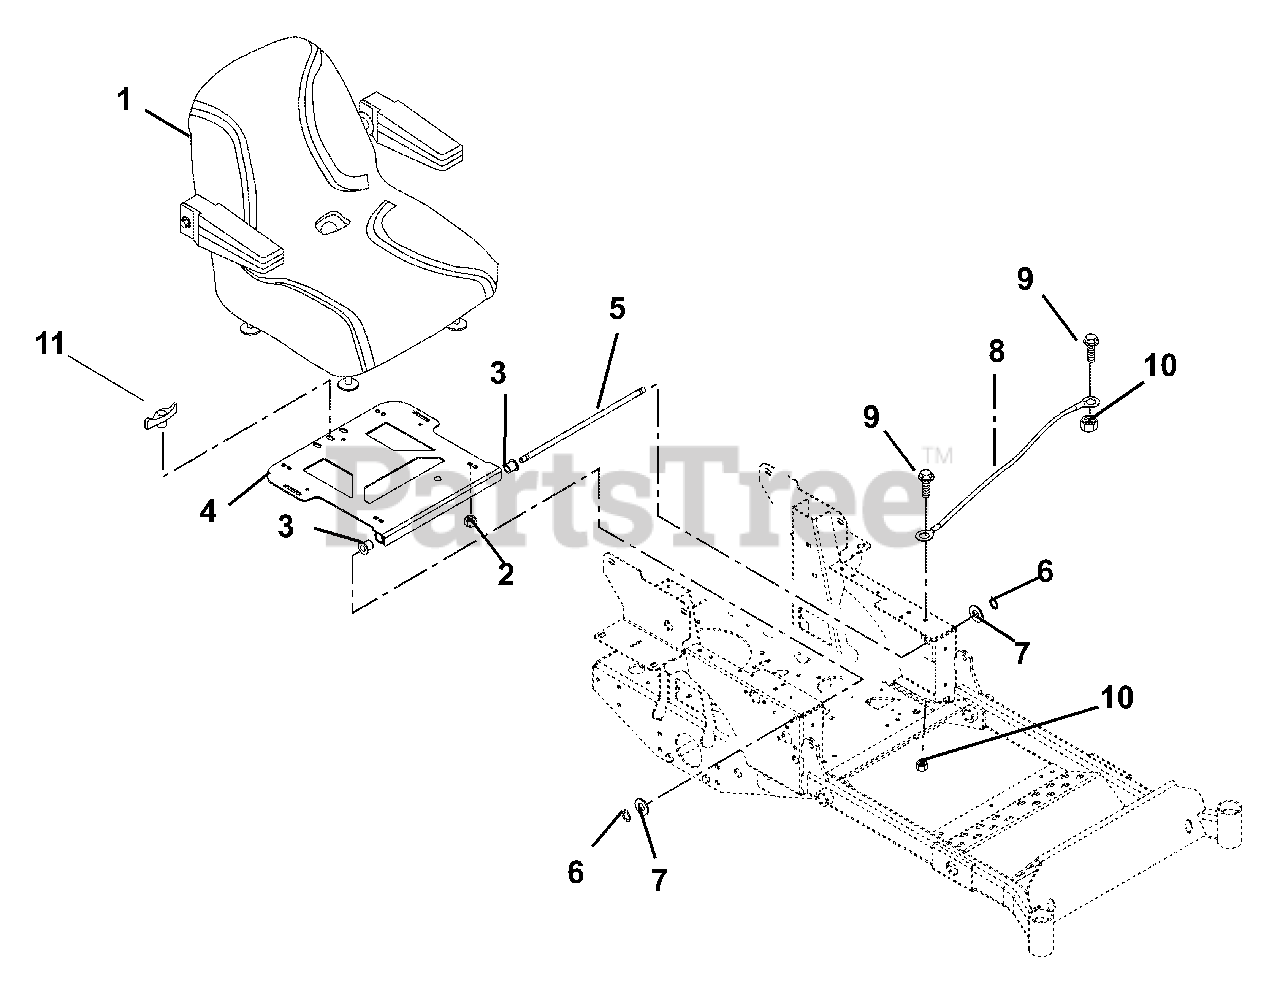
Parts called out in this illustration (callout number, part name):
1	ASSM, SEAT W/REPLA ARMRESTS
2	@NUT-LK-NYL-FLG .31-18 YWZC
3	BSHG-FLG .515X.750X.745X1.00NY
4	WMT, SEAT PIVOT MOUNT
5	ROD, SEAT FRAME PIVOT
6	RG-RTNG-EXT .500X.050 (SNAP)
7	@WSHR-FL-STL.531X1.06X.095YWZC
8	CBL,HOOD
9	@BLT-HEX .25-20X.75 GR5 YWZC
10	@NUT-LK-NYL-FLG .25-20 YWZC
11	KNOB - WING .312-18 UNC
